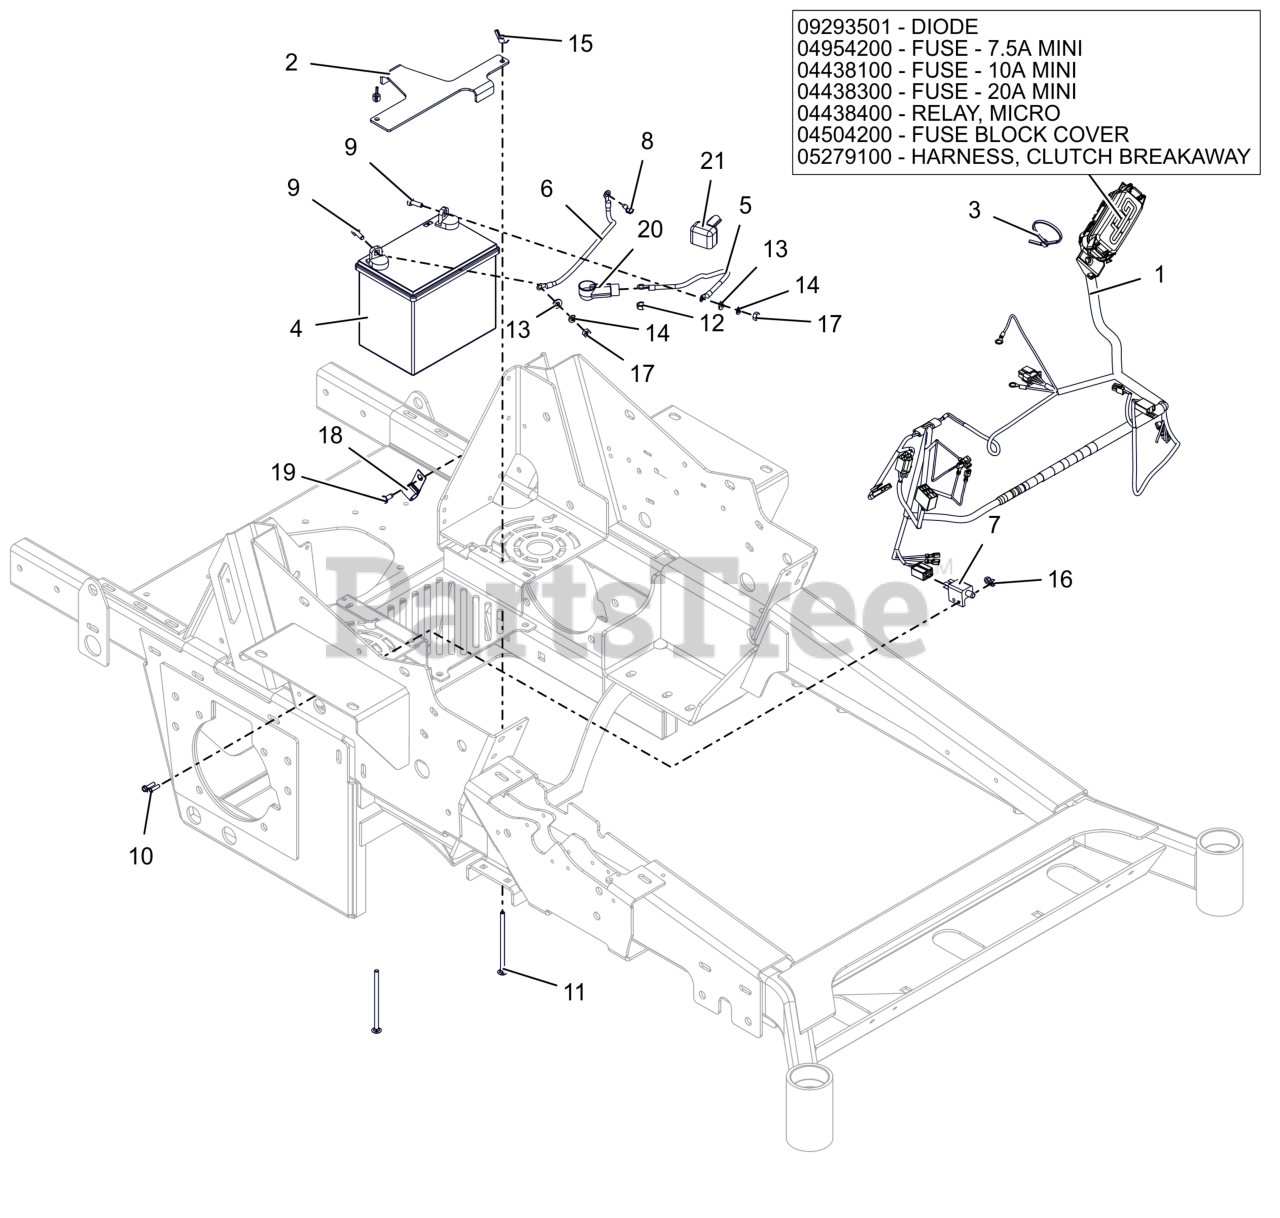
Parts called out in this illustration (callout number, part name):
1	HARNESS- WIRE PT300 MAIN
1	DIODE, CONNECTOR SHELL
1	FUSE, 7.5 AMP MINI-ATC
1	FUSE,10 AMP MINI-ATC
1	FUSE,20 AMP MINI ATC
1	RELAY,MICRO5 TERML W/RESISTOR
1	COVER, HARNESS FUSE/RELAY MOD
1	HARNESS, CLUTCH BREAKAWAY
2	HOLDDOWN- BATTERY
3	CABLE TIE, .15 X 8.50
4	BATTERY, 300 CCA 10U1L
5	CABLE, STARTER 13.00"
6	CABLE-GROUND .25 X 13.00 X .31
7	SWITCH- DOUBLE POLE N.O./N.O.
8	SCR-TAP .25-20X.50 HWH ZCC
9	BLT, HEX .25-20X.75 G5 ZCC
10	BLT, HWH #10-24X.75 ZCC
11	BLT, RHSN .25-20X4.50 G5 ZCC
12	NUT-HEX-JAM-CTR LK M8X1.25 ZCC
13	WSHR,FLT .281X.625X.065 ZCC
14	WSHR,LK-REG .250X.062 ZCC
15	NUT, LK-WING .25-20 ZCC
16	NUT-LK-NYL #10-24 G2 ZCC
17	NUT-STD .250-20 G2 ZCC
19	SCR,TAP .25-20X.625 HWH ZCC
20	BOOT, .65ID POS
21	INSULATOR
